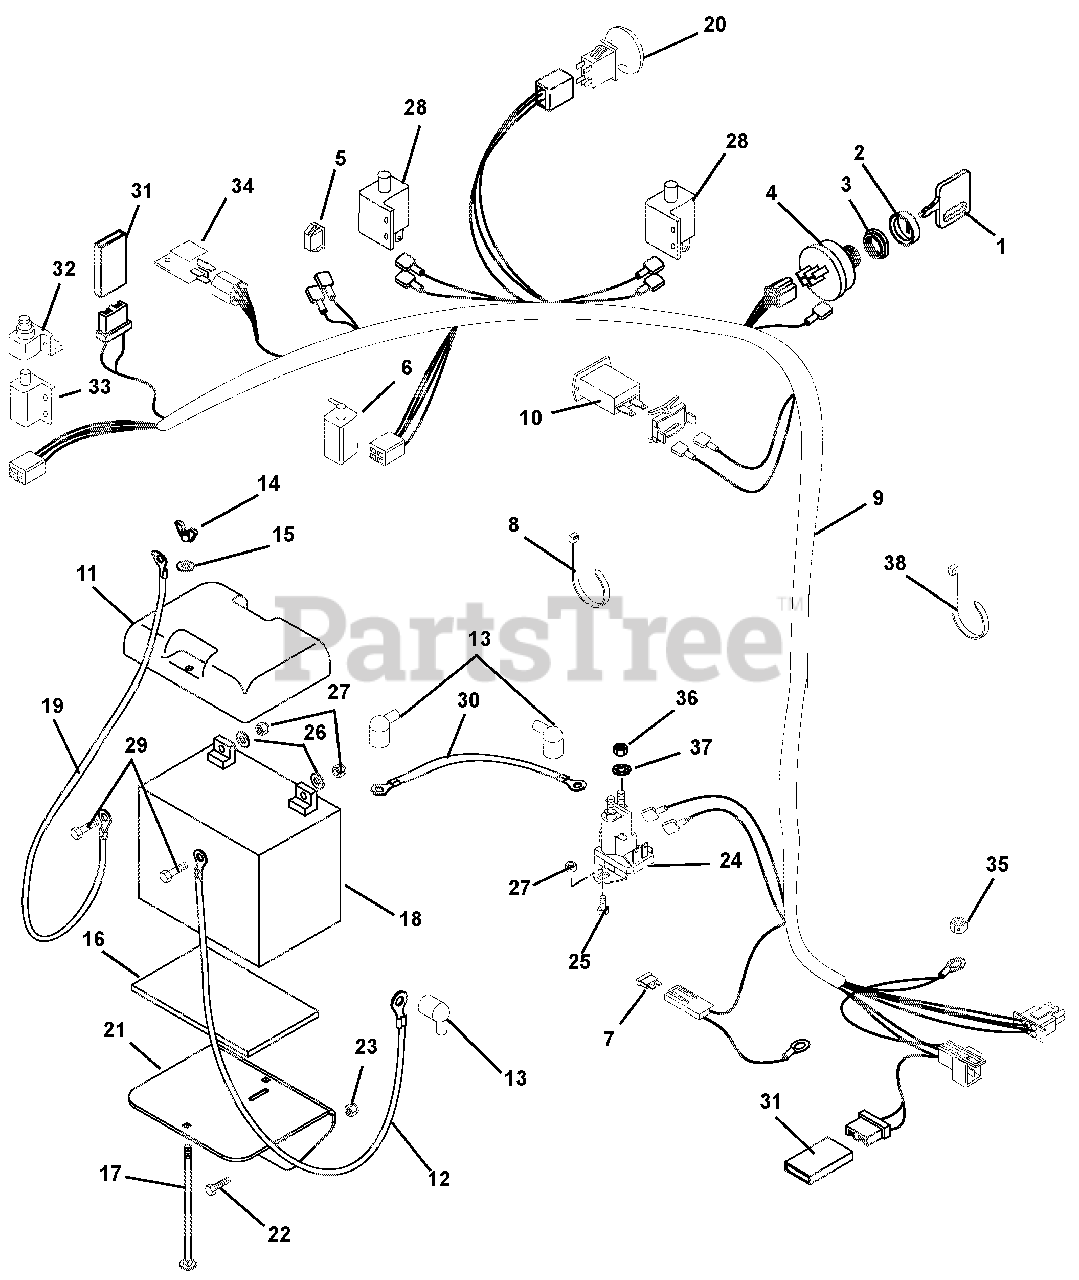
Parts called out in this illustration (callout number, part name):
1	Key- with Cap
2	Cap, Ignition Switch
3	Nut, Panel .625-32
4	Key Switch
5	Light, Indicator
6	Switch- Double Pole N.O./N.O.
7	Fuse-25 AMP
8	Tie Wrap-Black
9	Wire Harness
10	Hour Meter-Quartz
11	Cover-Battery
12	Cable, Positive Battery
13	Boot, Eyelet Terminal
14	Nut-Locking-Wing .25-20
15	Washer-Flat-Steel .281 x .625 x .065
16	Pad, Battery
17	Bolt-Round Head Square Neck .25-20 x 7.50 Grade 2
19	Cable, Negative Battery
20	Switch, Clutch With Retainer
21	Weldment, Battery Tray
22	Bolt-Hex .38-16 x 1.75 Grade 5
23	Nut-Locking-Nylon .38-16
24	Solenoid
25	Bolt-Hex .25-20 x .50 Grade 5
26	Washer-Flat-Steel .281 x .62 x .065
27	Nut-Locking-Flange .25-20
28	Switch- Single Pole (N.O.)
29	Bolt-Hex .25-20 x .75 Grade 5
30	Starter Cable 6.75"
31	Diode-Connector Shell
32	Boot, Rubber
33	Switch, Interlock
34	Relay
35	Nut-Locking-Top-Flange .31-18
36	Nut- Jam .31-24
37	Washer-Locking .31
38	Tie Wrap
